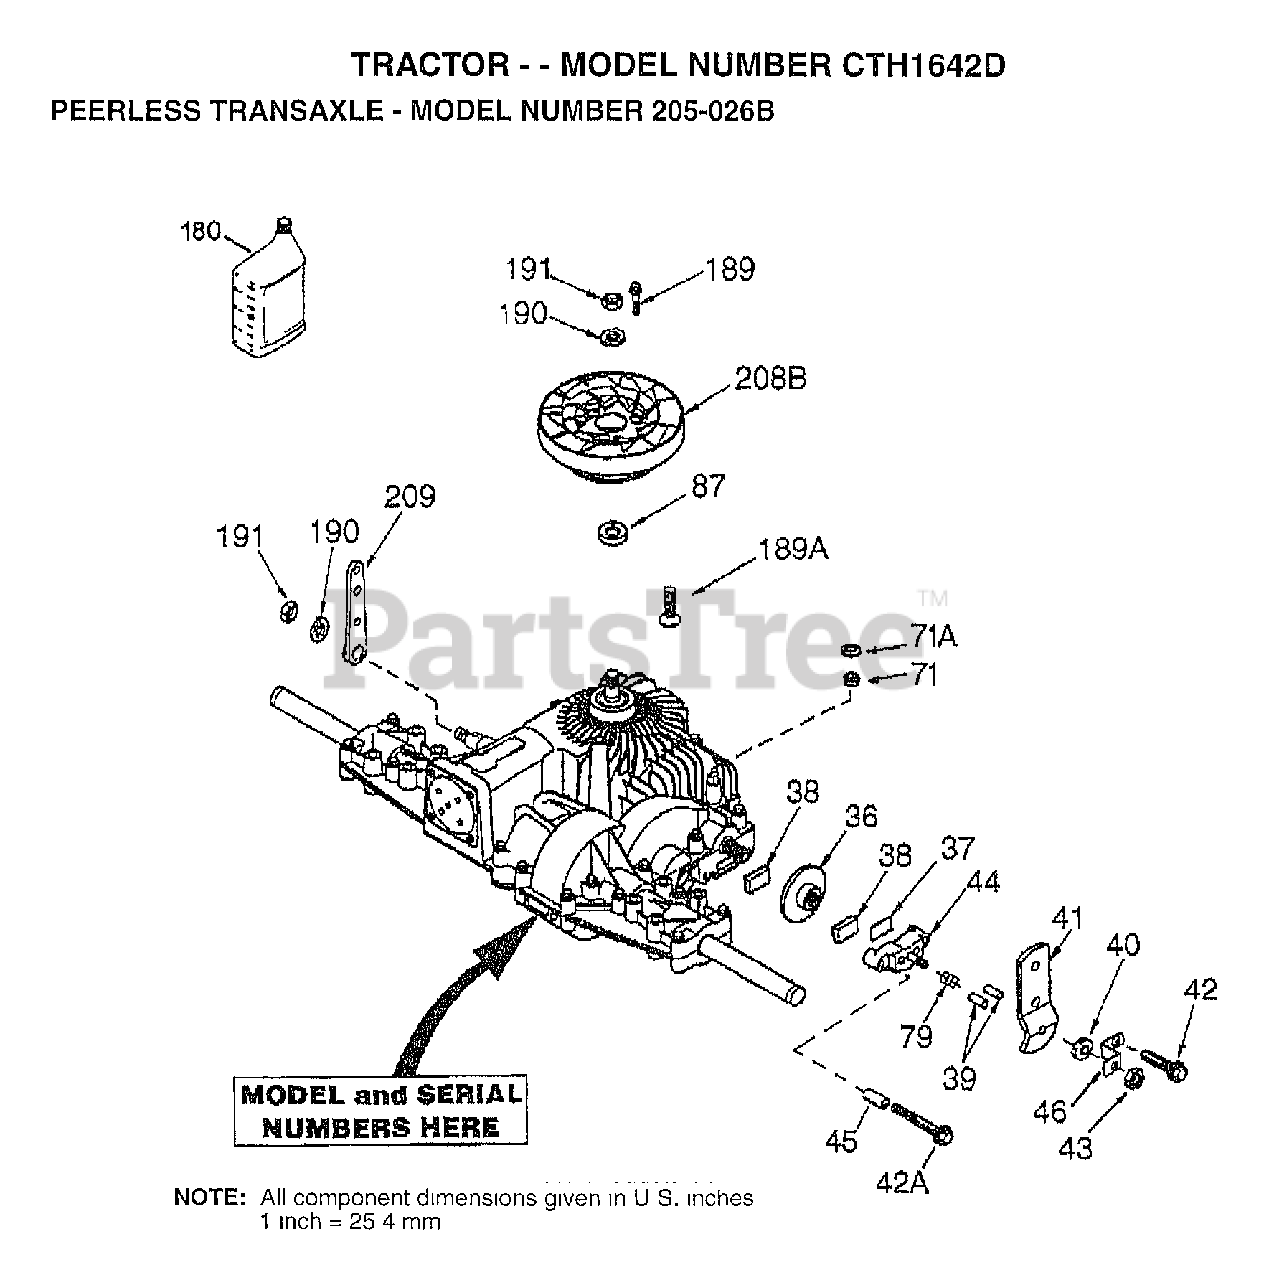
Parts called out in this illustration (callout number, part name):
37	PLATE BRAKE PAD
41	BRAKE LEVER
42	SCREW, 1/4-20 X 1-1/4
42A	SCREW, 1/4-20 X 2-1/4
43	LOCKNUT 5/16-24
44	HOLDER BRAKE PAD
46	BRAKE LEVER BRACKET
71	SEAL SQUARE CUT
180	GEAR OIL 80W90
189	DRIVE SCREW
208B	FAN/COUPLING
209	CONTROL LEVER
